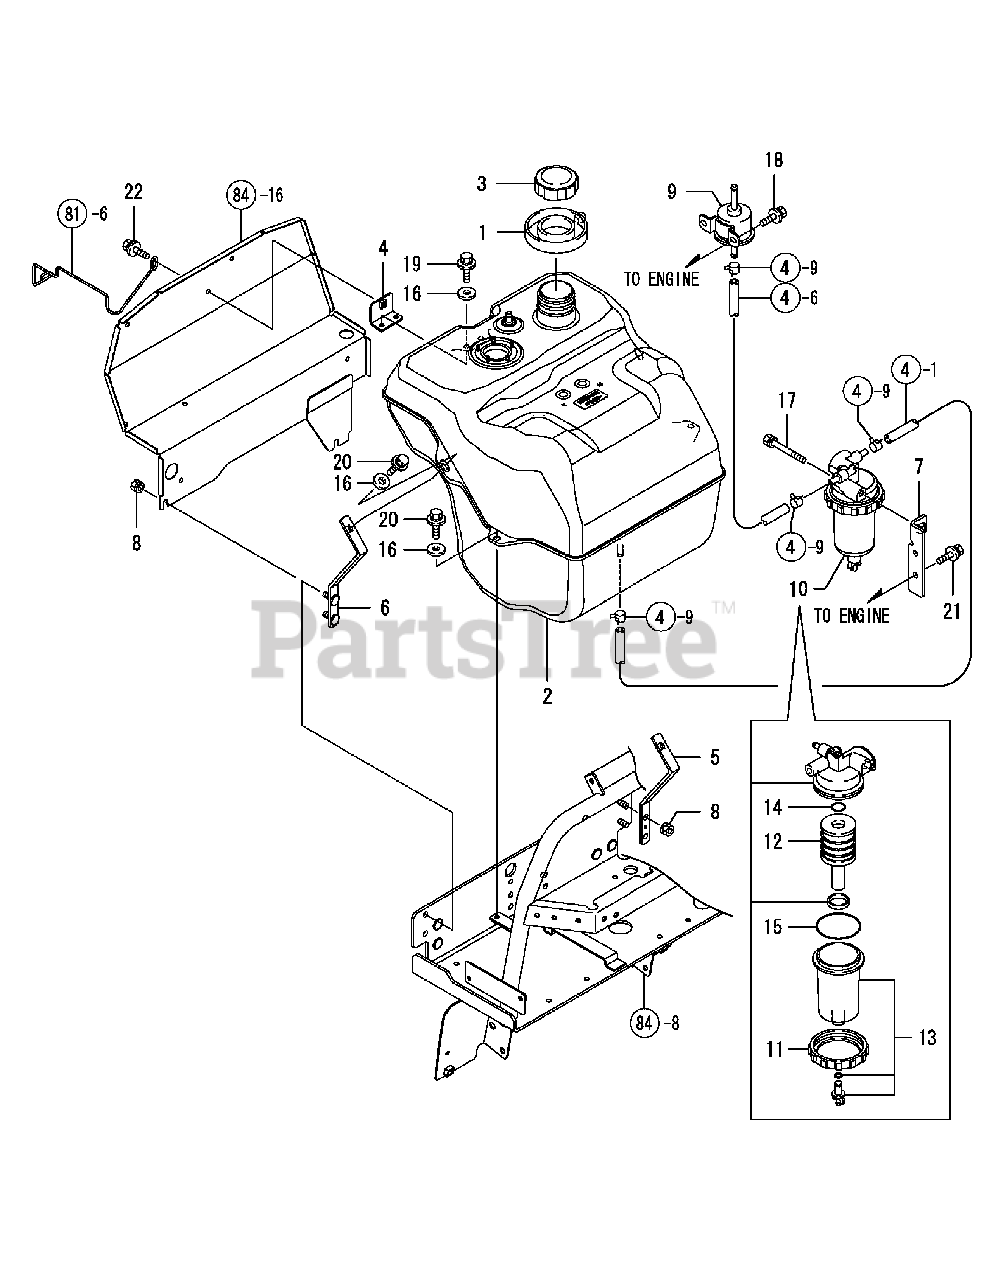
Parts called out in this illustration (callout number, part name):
3	Cap, Fuel Tank
4	Stay Assy, Tank F
5	Stay R Cmp, Tank
6	Stay Cmp, Tank
7	Stay Cmp,Separater
8	Nut W/Washer 8
9	Pump Assy, Fuel Feed
10	Separator Assy
11	Ring, Retaining
14	O-Ring 1A P-16.0
15	O-Ring 1A G-65.0
